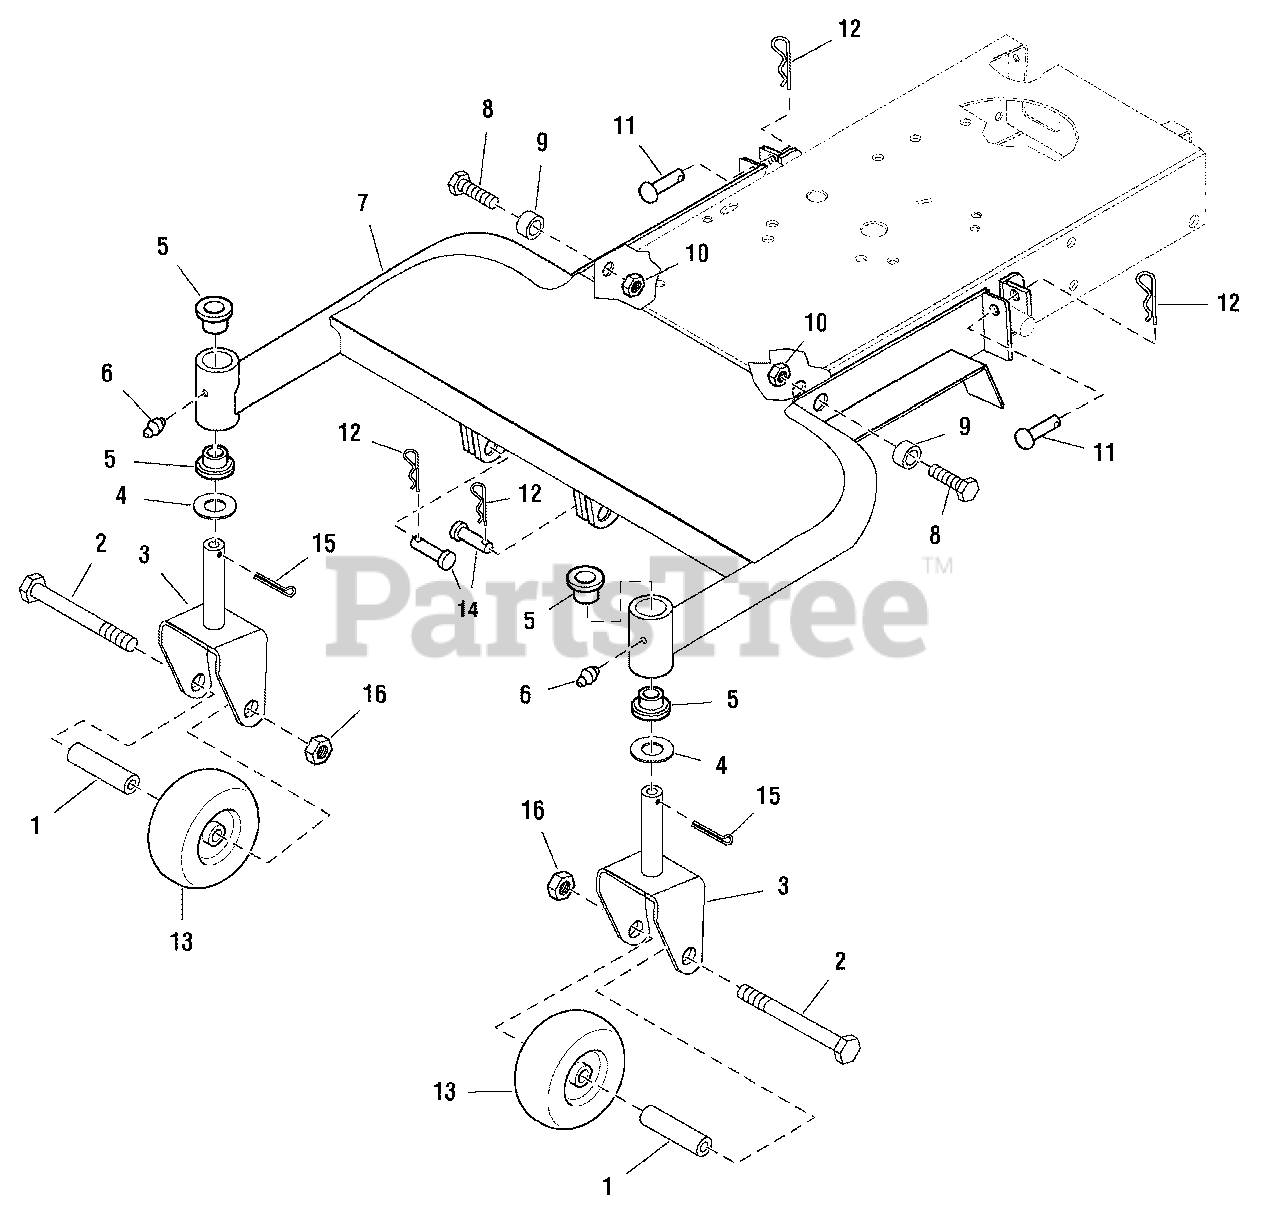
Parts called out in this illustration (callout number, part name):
2	CAPSCREW, Hex Head, 1/2-13 x 4-1/2, Black
3	BRACKET & SHAFT ASSEMBLY
4	WASHER, 3/4, Black
6	FITTING, Lube
7	FRAME ASSEMBLY
8	CAPSCREW, Hex Head, 3/8-16 x 1-1/4, Black
10	NUT, Hex Flange Lock, 3/8-16, Black
11	PIN, Round Head, Drilled, 3/8 x 2, Black
12	CLIP, Hair Pin, Black
13	WHEEL, Caster
14	PIN, Clevis, Black
15	PIN, Cotter,1/4 x 2, Black
16	NUT, Hex Lock Light, 1/2-13, Black
